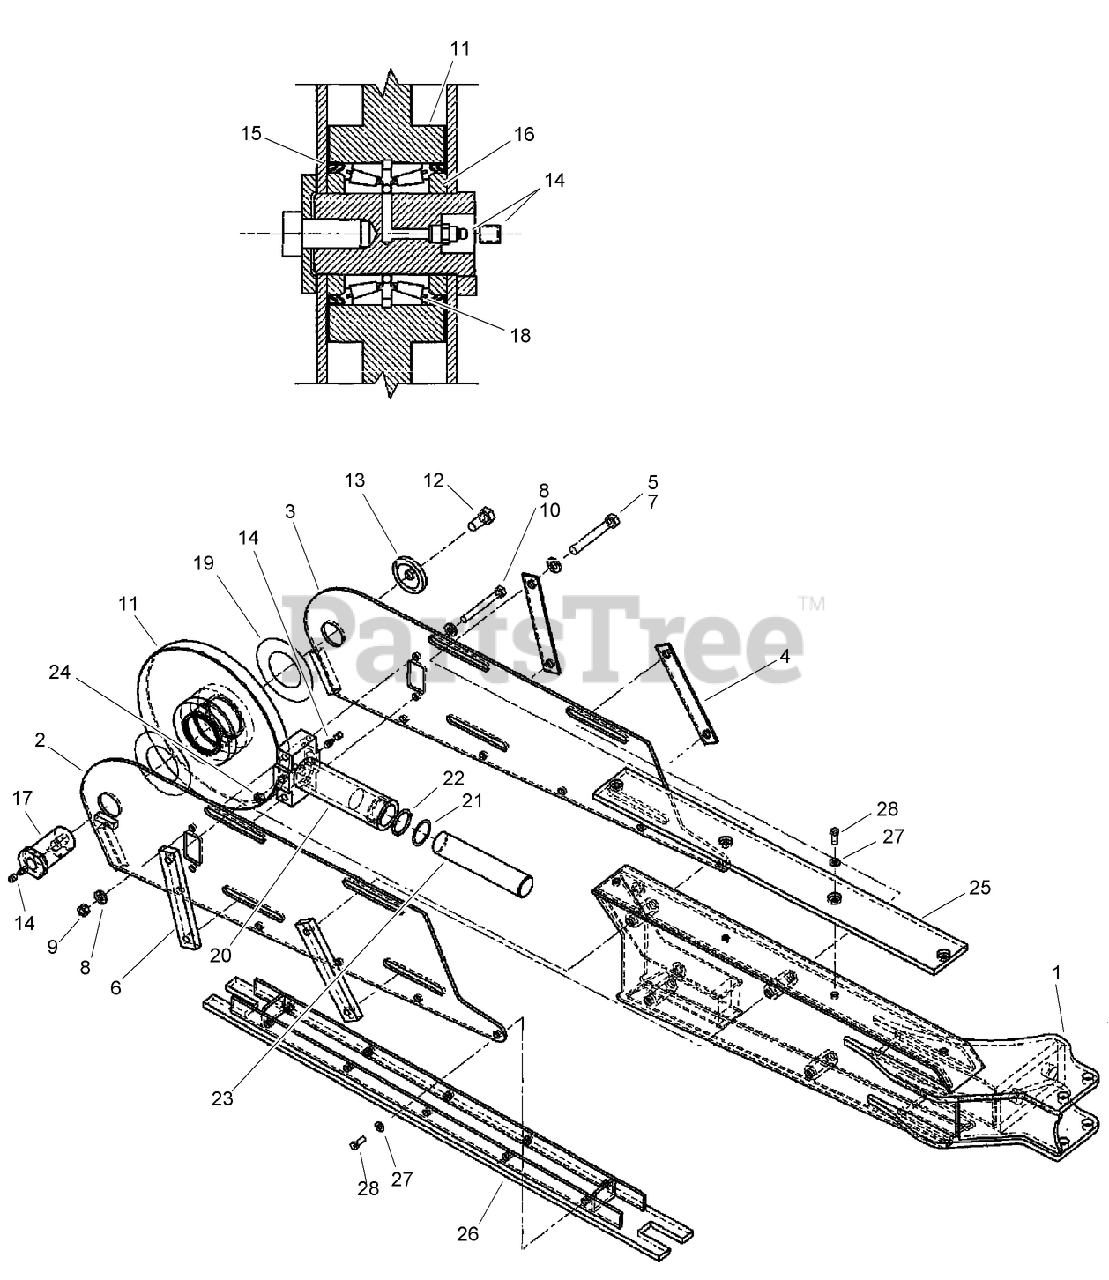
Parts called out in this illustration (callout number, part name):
1	BOOM-rock, 4 foot, direct drive trencher
2	PLATE-rock boom end, right-hand
3	PLATE-rock boom end, left hand
4	BAR-Clamp
5	WASHER-LOCK
6	BAR-Tapped
9	NUT-HEX
10	BOLT-hex, 1/2 NC x 4-1/4 inch
11	BOLLER-Boom End
14	FITTING-LUBE, STRAIGHT
15	SEAL-ROLLER
16	SPACER-bearing
17	PIN-BOOM
18	BEARING KIT
19	WASHER-BOOM, END (ROLLER)
20	CYLINDER-Boom End
21	WASHER-BACKUP
22	O-RING
23	ROD-BOOM, END (CYLINDER)
24	PLUG-BLEED
25	PAD-wear, upper
26	CHANNEL-wear pad, lower
27	WASHER-3/8 HT
28	SCREW-HH
